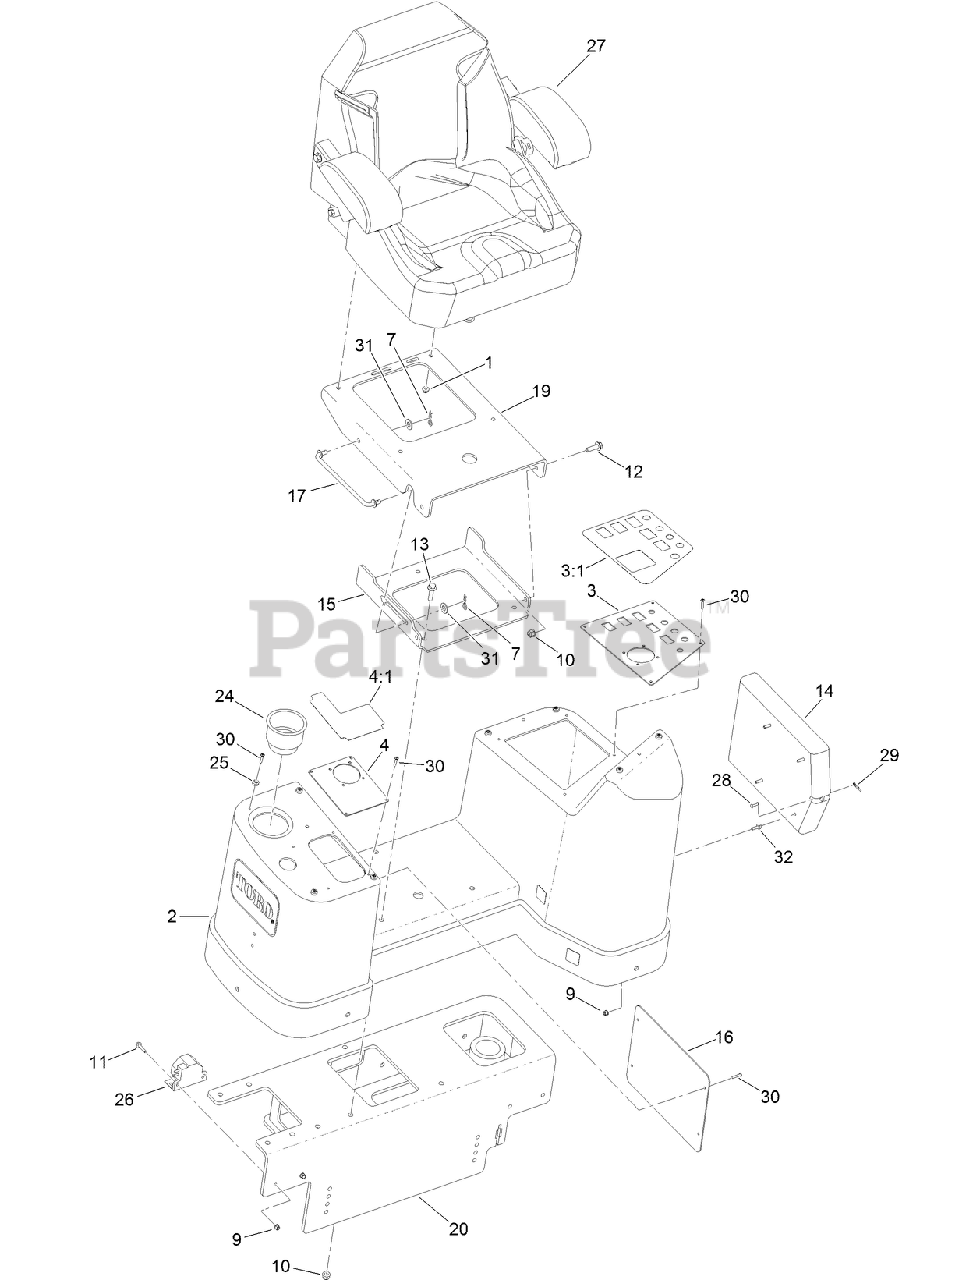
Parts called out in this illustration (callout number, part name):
1	NUT-HF, NI
2	OPERATOR CONSOLE ASM
3	SWITCH PLATE ASM
3:1	DECAL-LEFT JOYSTICK, DD4045
4	JOYSTICK MOUNTING PLATE ASM
4:1	DECAL-JOYSTICK, RIGHT
7	PIN-HAIR
9	NUT-FLANGE, NI
10	NUT-LOCK, NI
11	SCREW-HHF
12	SCREW-HHF
13	SCREW-HHF
14	HOLDER-MANUAL, OPERATOR
15	PLATE-SEAT MOUNT, BOTTOM
16	PLATE-SEAT, INSIDE PANEL
17	ROD-PROP, SEAT
19	PLATE-SEAT MOUNT, TOP
20	CONSOLE-OPERATORS
24	CUP-HOLDER
25	GROMMET-RUBBER
26	ALARM-BACKUP
27	SEAT-TORO, STANDARD
28	POST-MANUAL
29	LANYARD
30	SCREW-PPH
31	WASHER-FLAT
32	SCREW-HHF
